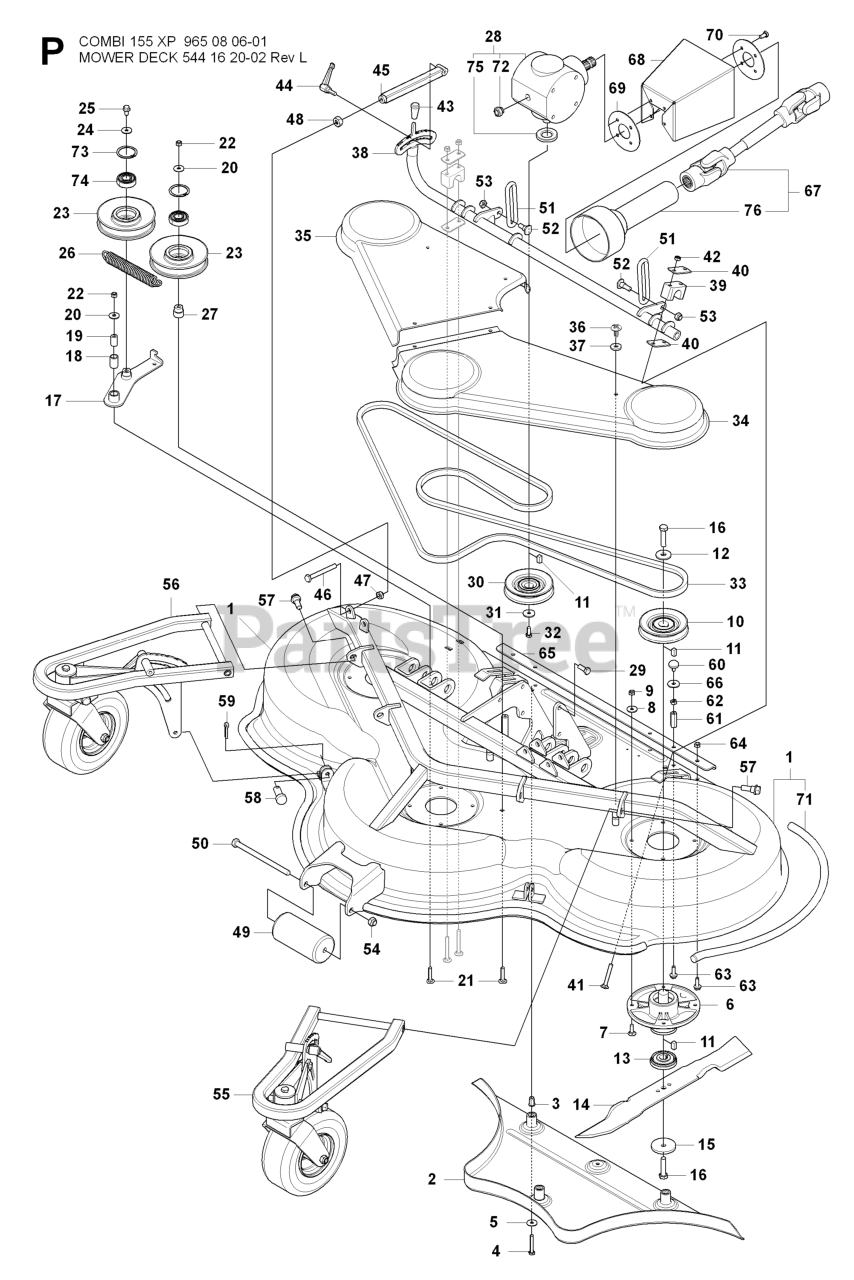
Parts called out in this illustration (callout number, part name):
2	PLUG ASSEMBLY
3	BLIND RIVET NUT
5	WASHER BRB 8.4X17
8	WASHER BRB 8.4X17
9	LOCKNUT M8
17	BELT TENSIONER CUTTING DECK
21	Screw Mvbf 8 X 40
22	LOCKNUT M8
25	BOLT FLANGE - M8X16
26	DRAW SPRING L=122
28	BEVEL GEAR
29	Screw M10x25
30	PULLEY SPB DP106
32	SCREW 8X20
34	BELT COVER C155 L
39	BEARING COVER
42	LOCKNUT M8
44	TURNING KNOB M 8
45	PARALLEL ROD NOT IN USE
48	NUT
49	ROLLER
52	SCREW LINK
53	NUT
55	WHEEL SUSPENSION LEFT
56	WHEEL SUSPENSION RIGHT
60	ANTIVIBRATION ELEMENT
62	NUT
64	LOCKNUT M8
65	REINFORCING PLATE DECK SHELL
70	REPL BY 725 24 49-51
73	CIRCLIP SGH 47
74	BALL-BEARING 6204-2RS
